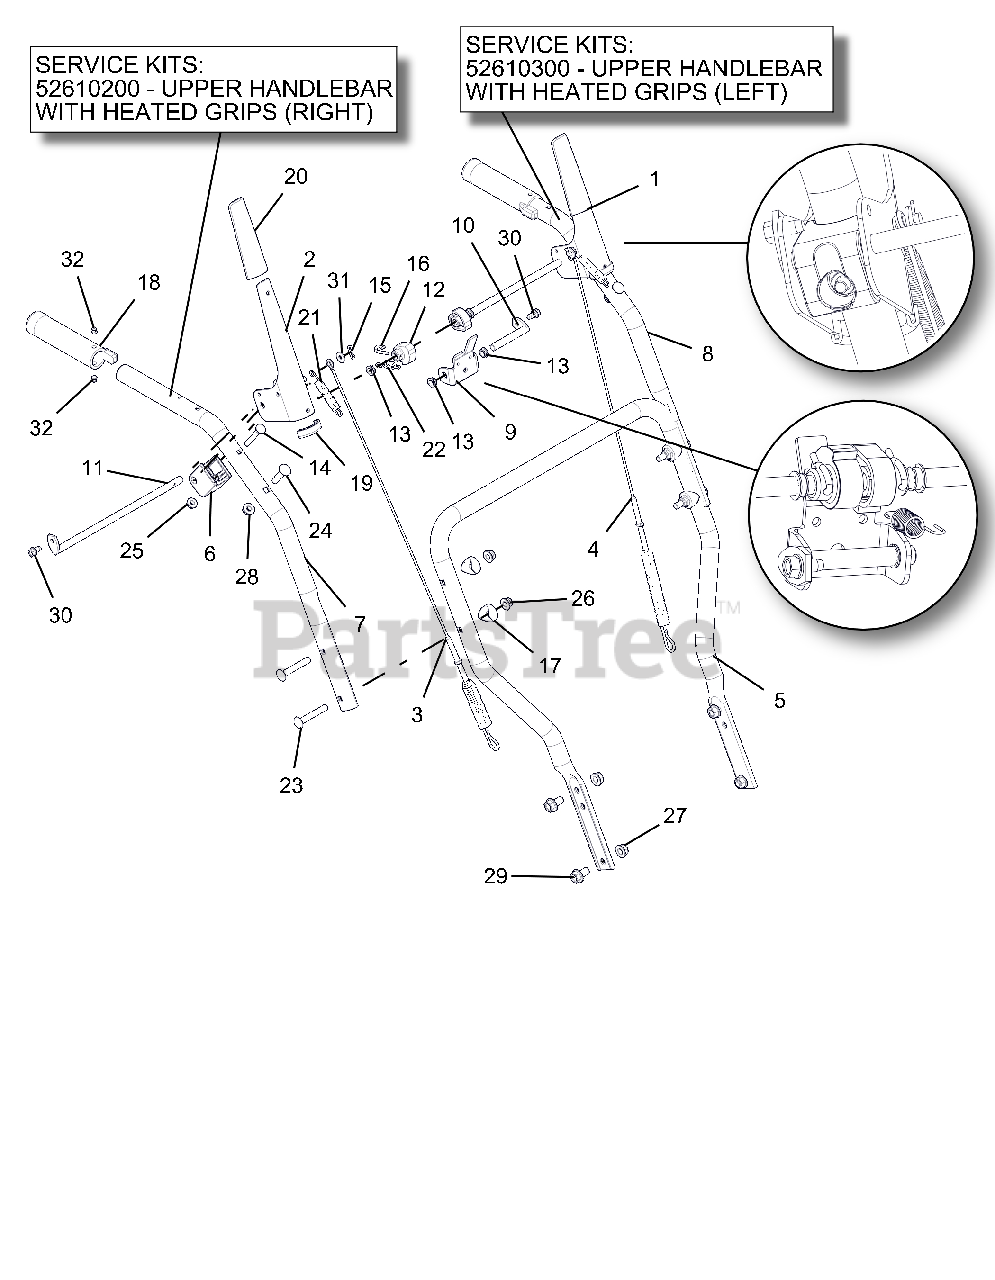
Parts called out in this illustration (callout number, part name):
1	LEVER, CLUTCH-LH
2	LEVER, CLUTCH-RH
3	CABLE, AUGER (DELUXE & PRO)
4	CABLE, UPPER TRACTION
5	HANDLEBAR, LOWER
6	BLOCK, CLUTCH PADDLE
7	HANDLEBAR, UPPER - RH
7	HANDLEBAR, UPPER RH W/HW
8	HANDLEBAR, UPPER - LH
8	HANDLEBAR, UPPER LH W/HW
9	BRACKET, INTERLOCK ARM
10	ROD, PIVOT - INTERLOCK
11	ROD, PADDLE MOUNT - PRO
12	CAM, INTERLOCK
13	BUSHING, POLYLINER-.38 SNAPIN
14	BLT-RDHDXLSQNK .25-20X2.0 G5YZ
15	PIN-HAIR INT .06X.18X.77
16	PIN, SPRING CLIP
17	SPACER, HANDLEBAR
18	HEATED GRIP, MAGURA
19	EDGING, CLUTCH PADDLE - 2.00"
20	CLUTCH PADDLE SLEEVE - GRAY
21	SPRING, EXTENSION
22	SPRING-EXT .047X.438X1.45
23	@BLT-RDHDSQNK .31-18X2.25 G5YZ
24	@BLT-RDHDSQNK .31-18X1.50 G5YZ
25	@NUT-LK-CTR-FLG .25-20 YWZC
26	@NUT-LK-NYL-FLG .31-18 YWZC
27	@NUT-LK-TOP-FLG .38-16 YWZC
28	@NUT-LK-TOP-FLG .31-18 YWZC
29	BLT-SERHFWH .38-16X.75 YWZC
30	SCR-TAP .25-20X.50 HWH TR YWZ
31	@WSHR-FL-STL.281X.62X.065 YWZC
32	RVT-POP #43 .125X.313 STL ZINC
